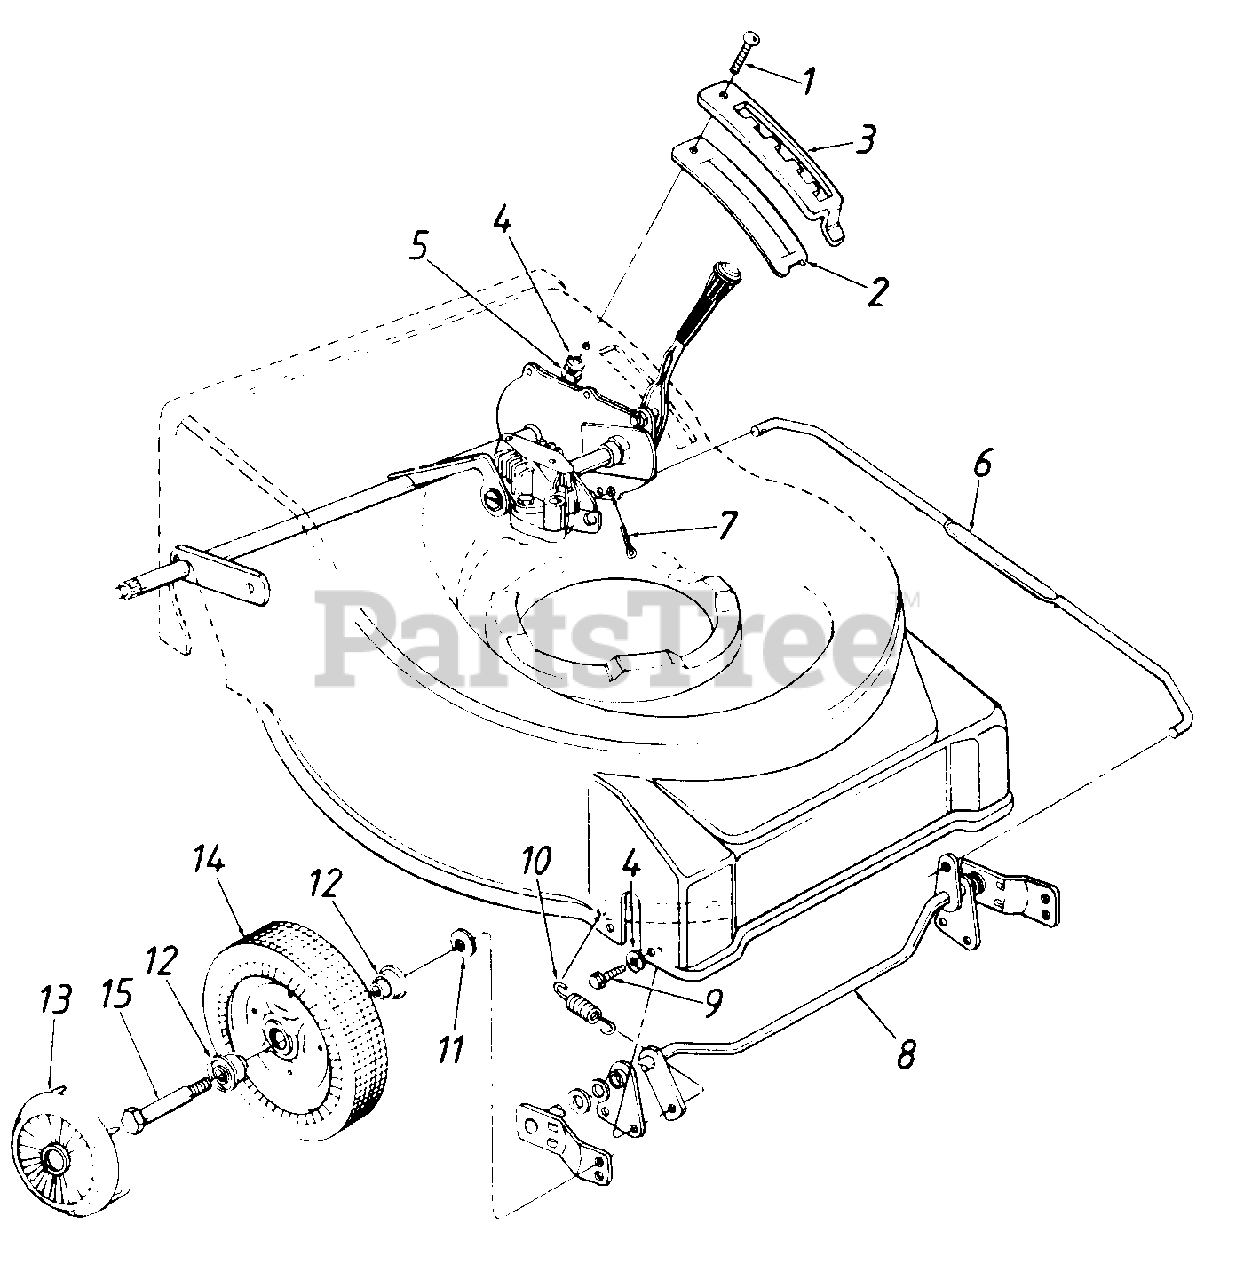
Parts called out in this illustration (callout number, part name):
1	Torx Mach. AB-Tap Scr. 1/4" x .62" Lg.
2	Height Adjustment Support
3	Height Adjustment Plate
4	FL-Wash. 1/4" I.D.
5	Hex Nut 1/4-20 Thd.
6	Height Adj. Connecting Rod
7	Cotter Pin 3/32" Dia.
9	Hex L-Wash. Hd. AB-Tap Scr .1/4 x.38" Lg.
10	Extension Spring 2.39" Lg.
11	Bell-Wash. .380" I.D. x .88" O.D.
12	Flange Ball Bearing 1/2" I.D.
13	Hub Cap
14	Wheel Ass'y. Comp.-Front
15	Shld. Bolt .498" Dia. x 1.45
